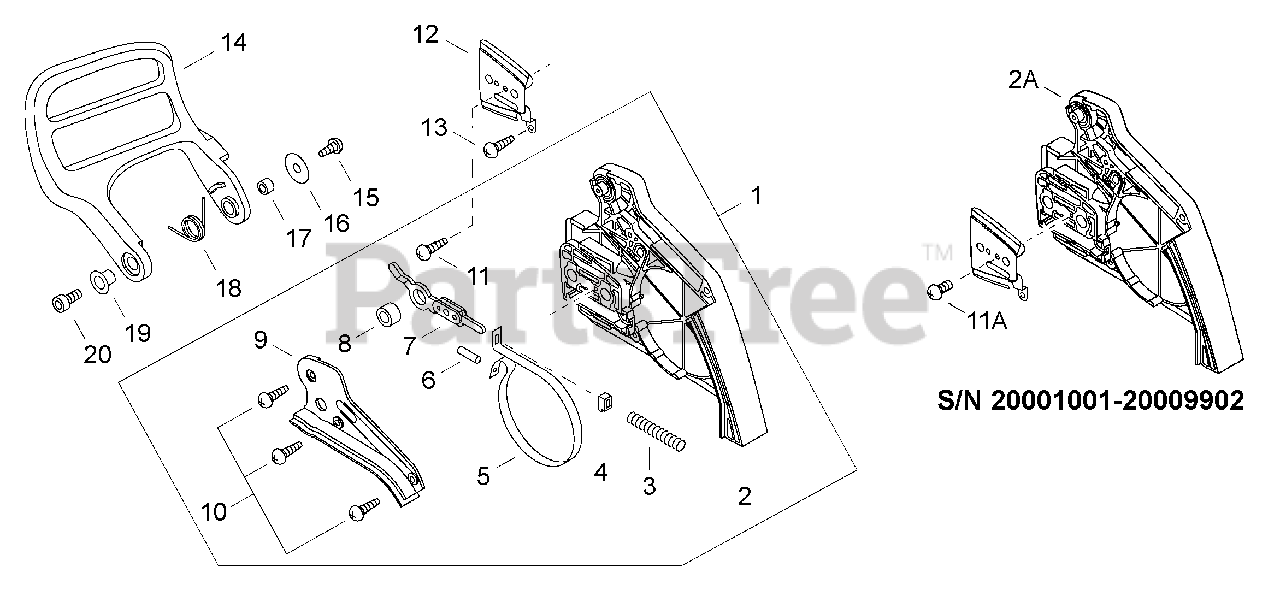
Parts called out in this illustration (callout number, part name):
1	CHAIN BRAKE ASSY
2	GUARD, SPROCKET
2A	COVER, CLUTCH
5	BAND, BRAKE
6	PIN - SPRING
7	CONNECTOR, BRAKE
8	SPACER - 8
9	COVER, BRAKE
10	SCREW - 4X12 -- TAPPING
11	SCREW - 3X5
11A	SCREW - 3X16
12	PLATE, GUIDE - OUTER
13	SCREW - 4X12 -- TAPPING
14	LEVER, BRAKE
15	SCREW - 4X16
17	SPACER - 8
19	COLLAR - 10
20	SCREW - 5X16
